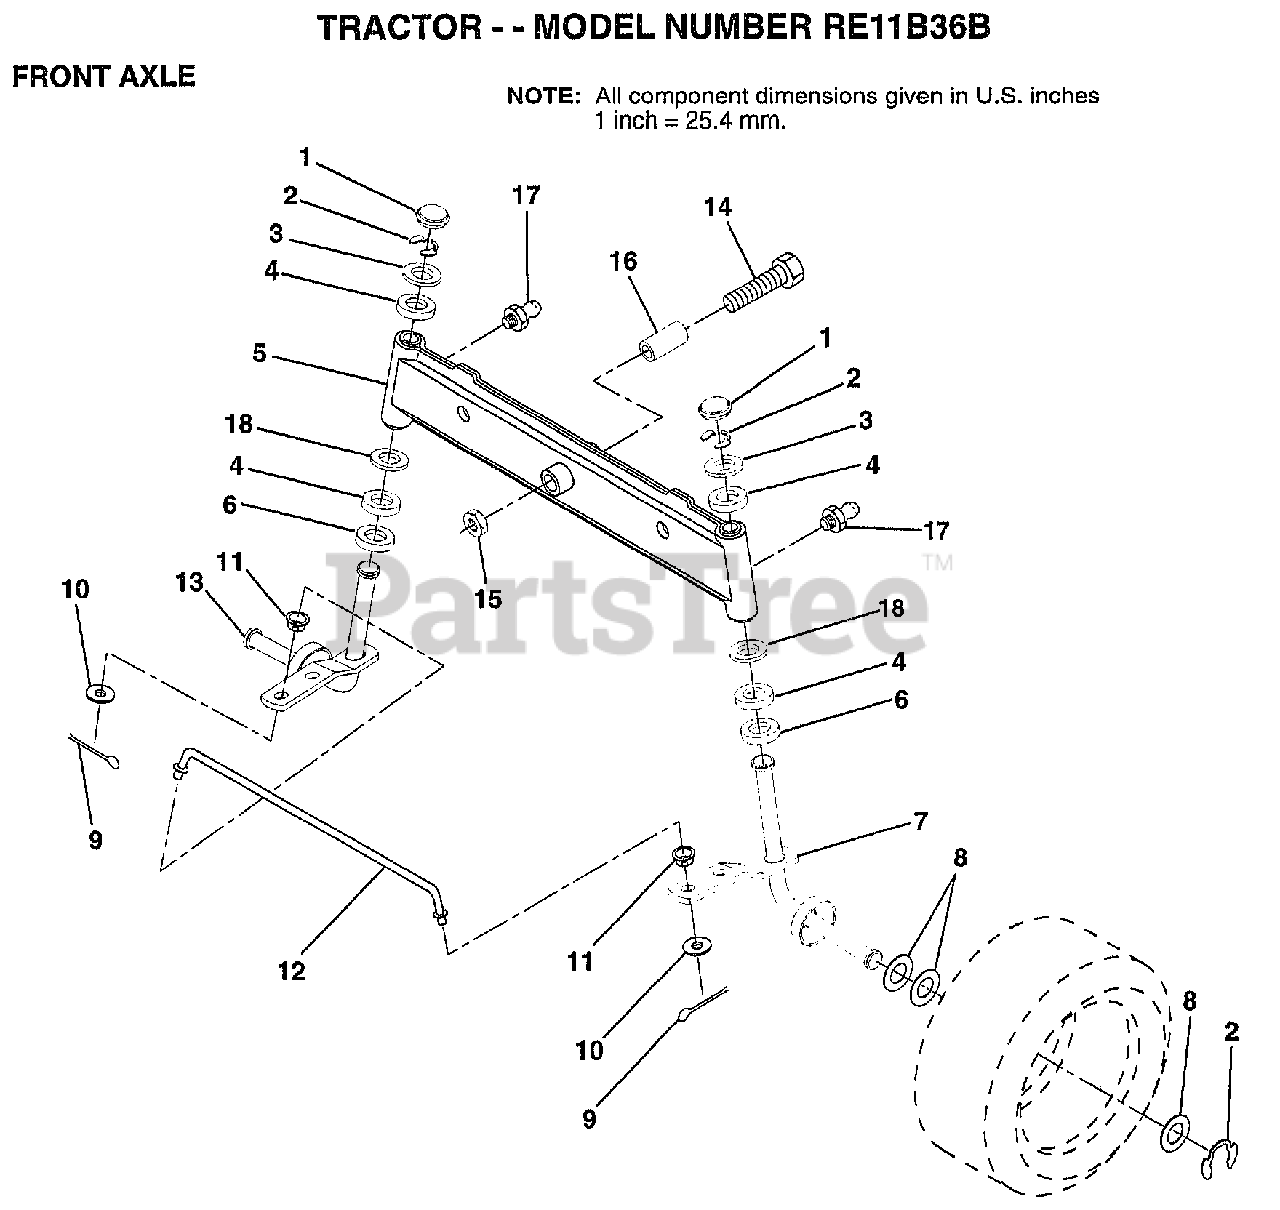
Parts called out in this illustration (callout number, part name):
1	CAP
2	RING
3	WASHER
4	COL. SRTG. BEAR.
5	AXLE ASM FRONT
6	WASHER .T
7	SPINDLE.ASSY.RH
8	WASHER
9	COTTER PIN
10	WASHER
11	BUSHING.DRAGLINK
12	TIE ROD
13	SPINDLE.ASSY.LH
14	BOLT HEX 5/8-11
15	"NUT-LOC,FLANGE LT"
16	BEARING
17	ZERK M
18	WASHER
